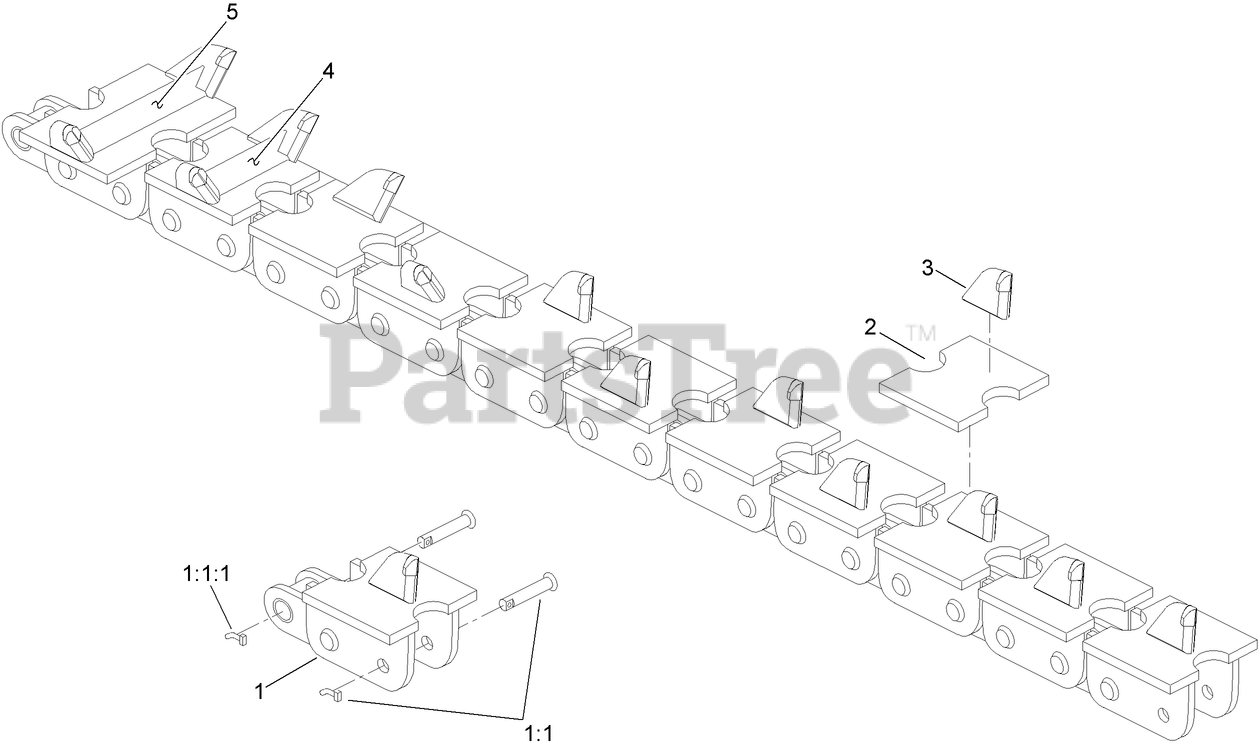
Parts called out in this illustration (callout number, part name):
1	CHAIN REPAIR LINK ASM
1:1	NOTCHED PIN AND KEEPER ASM
1:1:1	PIN-KEEPER
2	PLATE-H, WELD-ON
3	TOOTH-TERMINATOR, WELD-ON
4	DRAG-DIRT, WELD-ON (6.00)
5	DRAG-DIRT, WELD-ON (8.00)
